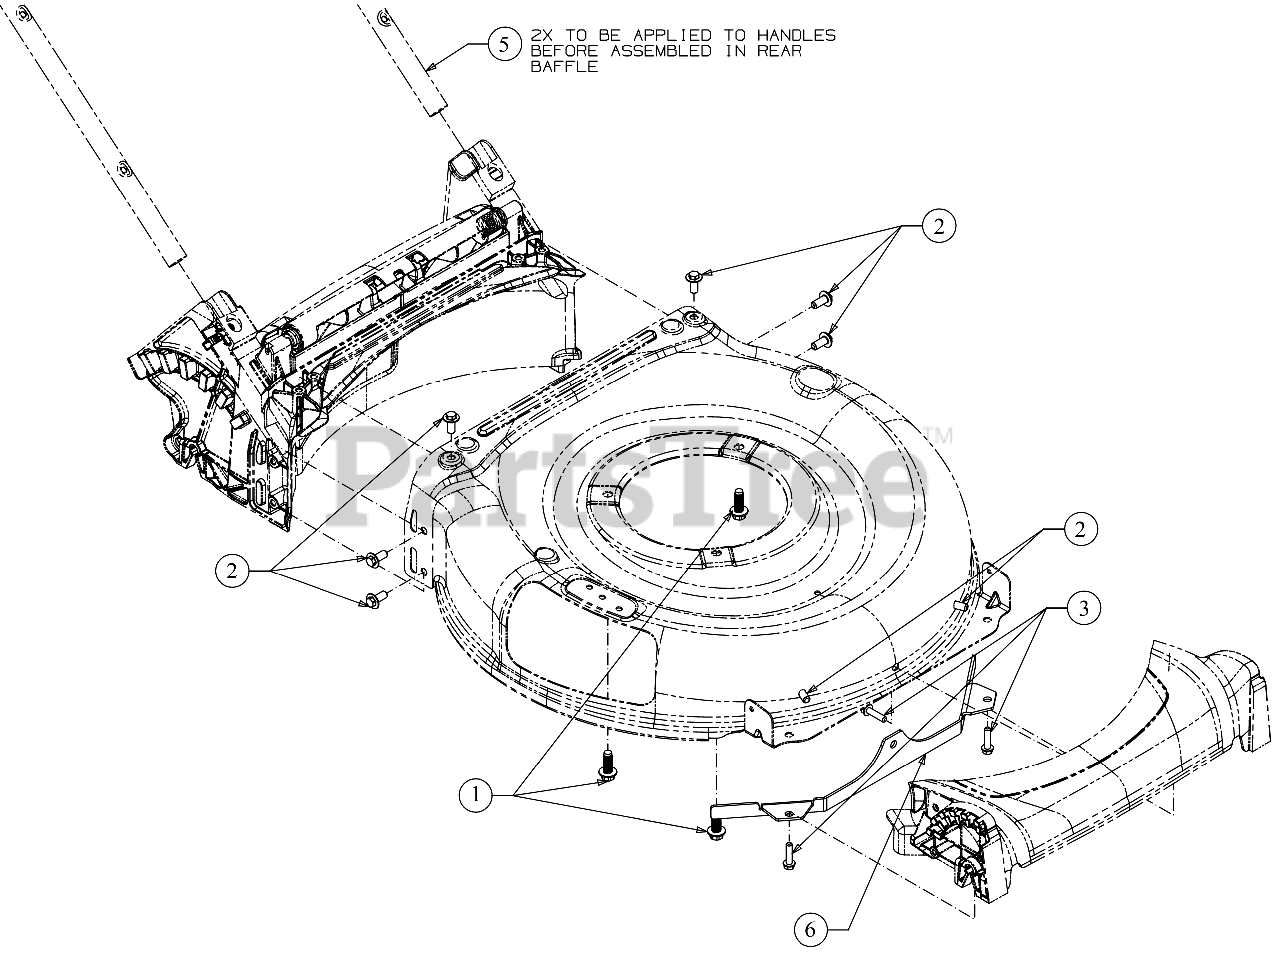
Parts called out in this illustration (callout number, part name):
1	SCREW 3/8-16 X 1
2	SCREW 5/16-14 X .750
3	SCREW 5/16-14 X 1
